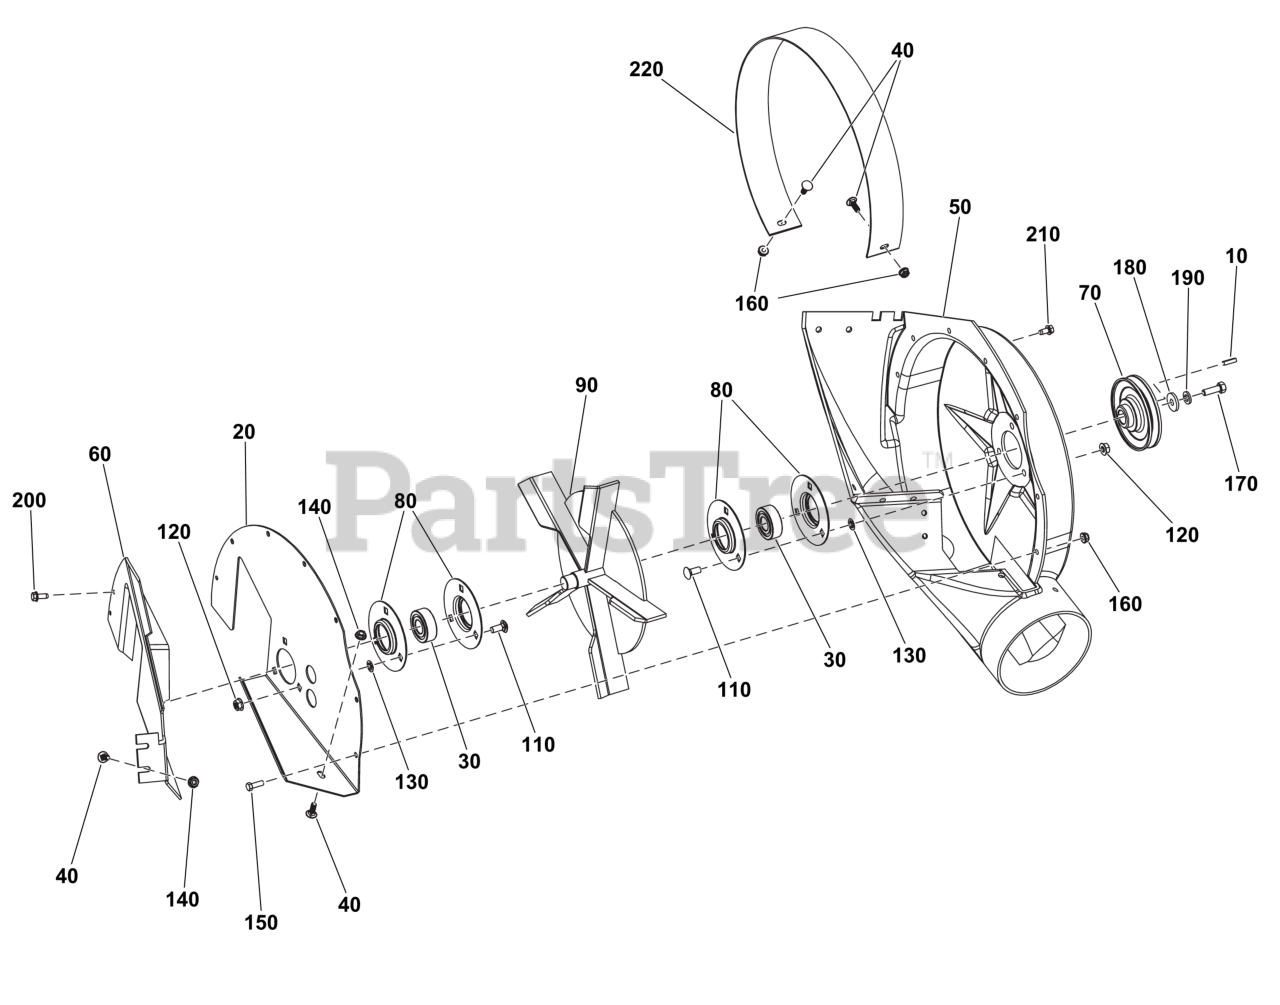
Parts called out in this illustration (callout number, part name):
10	KEY, SQUARE
30	BEARING, BALL
40	BOLT, 1/4-20X.750, SQ
50	HOUSING, FERRIS TURBO BLOWER
60	PLATE-COVER,BLACK POL
80	BEARING RETAINER - PL
90	IMPELLER
110	BOLT, 5/16-18 X 3/4",
120	NUT, 5/16-18 HEX SERR
130	NUT, PUSH ON, 5/16
150	BOLT,1/4-20X5/8
180	WASHER, 5/16
190	WASHER, 5/16" LOCK
200	SCREW, 1/4-20X0.625
210	SCREW, HEX, 1/4-20X.5
220	RING, TURBO VAC, INTERNAL
